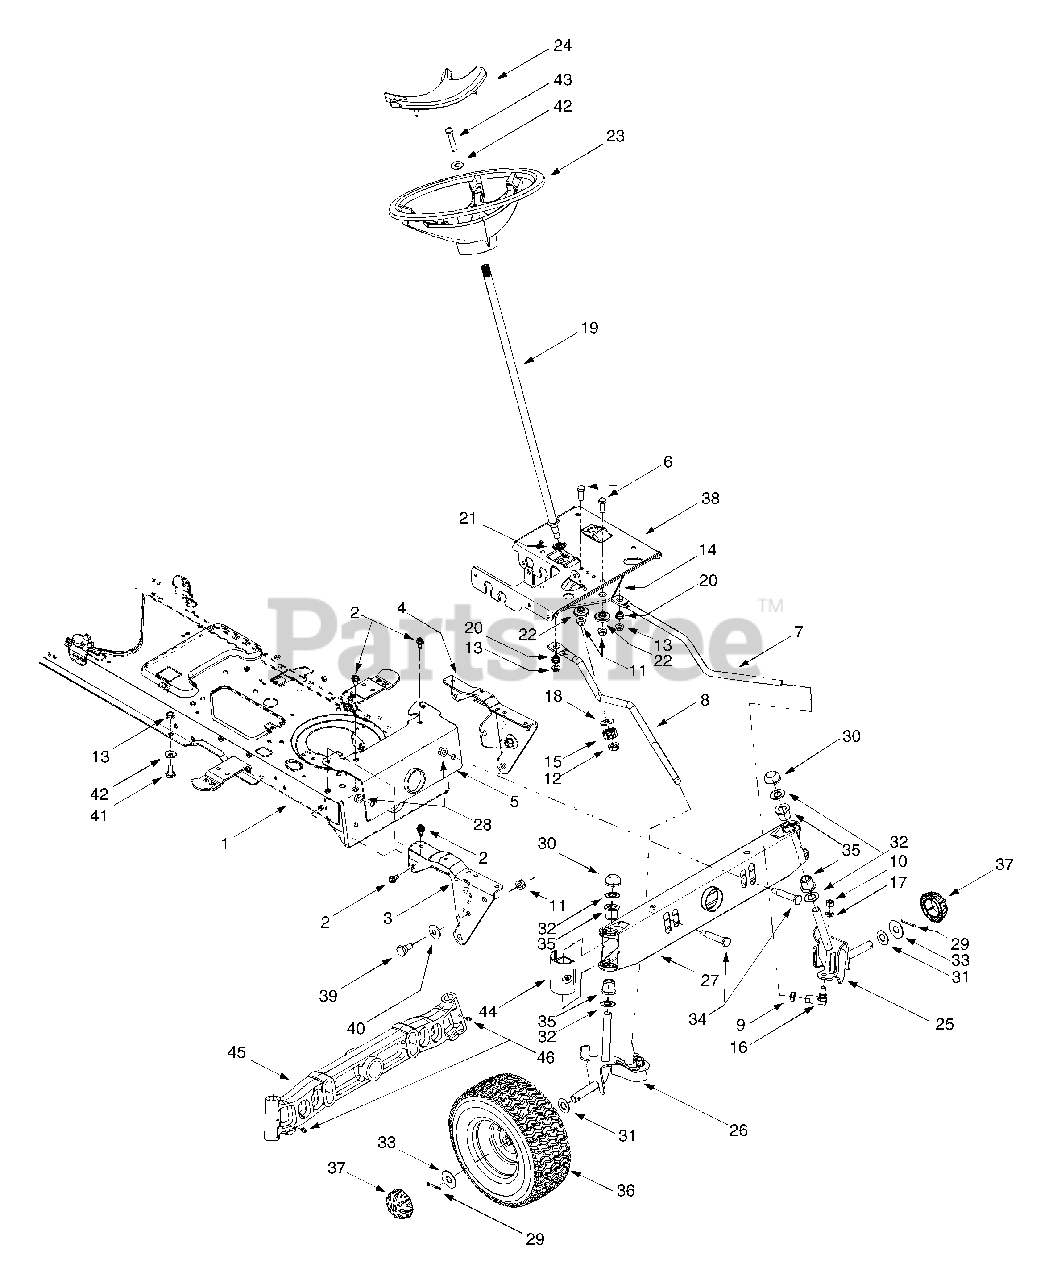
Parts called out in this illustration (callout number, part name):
6	Hex Cap Screw, 3/8-16 x 1 (Grade 5)
7	LH Drag Link
8	RH Drag Link
9	Jam Nut, 7/16-20 (Grade 2)
10	Hex Nut, 3/8-24 (Grade 2)
11	Flange Lock Nut, 3/8-16
12	Flange Lock Nut, 7/16-20
13	Flange Lock Nut, 5/16-18
14	Steering Gear, 11/90 Ratio
15	Steering Pinion Gear
16	Ball Joint, 7/16-20
17	Lock Washer, 3/8
18	Flat Washer, .51 x 1.12 x .06
19	Steering Shaft, .625 OD x 24.4
20	Plastic Bushing, .38 ID
21	Hex Flange Bearing, 5/8
22	Shoulder Spacer, .38 ID
23	Steering Wheel
24	Steering Wheel Cap w/ Icon
25	LH Axle Assembly, .625 Diameter
25	LH Axle Assembly, .625 / .750 Diameter
26	RH Axle Assembly, .625 Diameter
26	RH Axle Assembly, .625 / .750 Diameter
28	Flange Lock Nut, 3/8-16
29	Cotter Pin
30	Push Cap, .625
30	Push Cap, .750
31	Flat Washer, .64 x 1.0 x .12
32	Flat Washer, .64 x 1.24 x .06
32	Flat Washer, .78 x 1.59 x .06
33	Flat Washer, .635 x 1.589 x .06
34	Shoulder Screw, .5 x 2.2, 3/8-16
35	Flange Bearing, .632 ID x .937 OD
35	Flange Bearing, .760 ID x .937 OD
37	Hub Cap
39	Shoulder Screw, 3/8-16
40	Bell Washer, .39 x 1.13 x .062
41	Shoulder Screw, .435 x .178, 5/16 x .56
42	Bell Washer, .34 x .872
43	Hex Bolt, 5/16-18 X 1
44	Pivot Bar End Cap
45	Cast Iron Pivot Bar
46	Lube Fitting, 3/16
